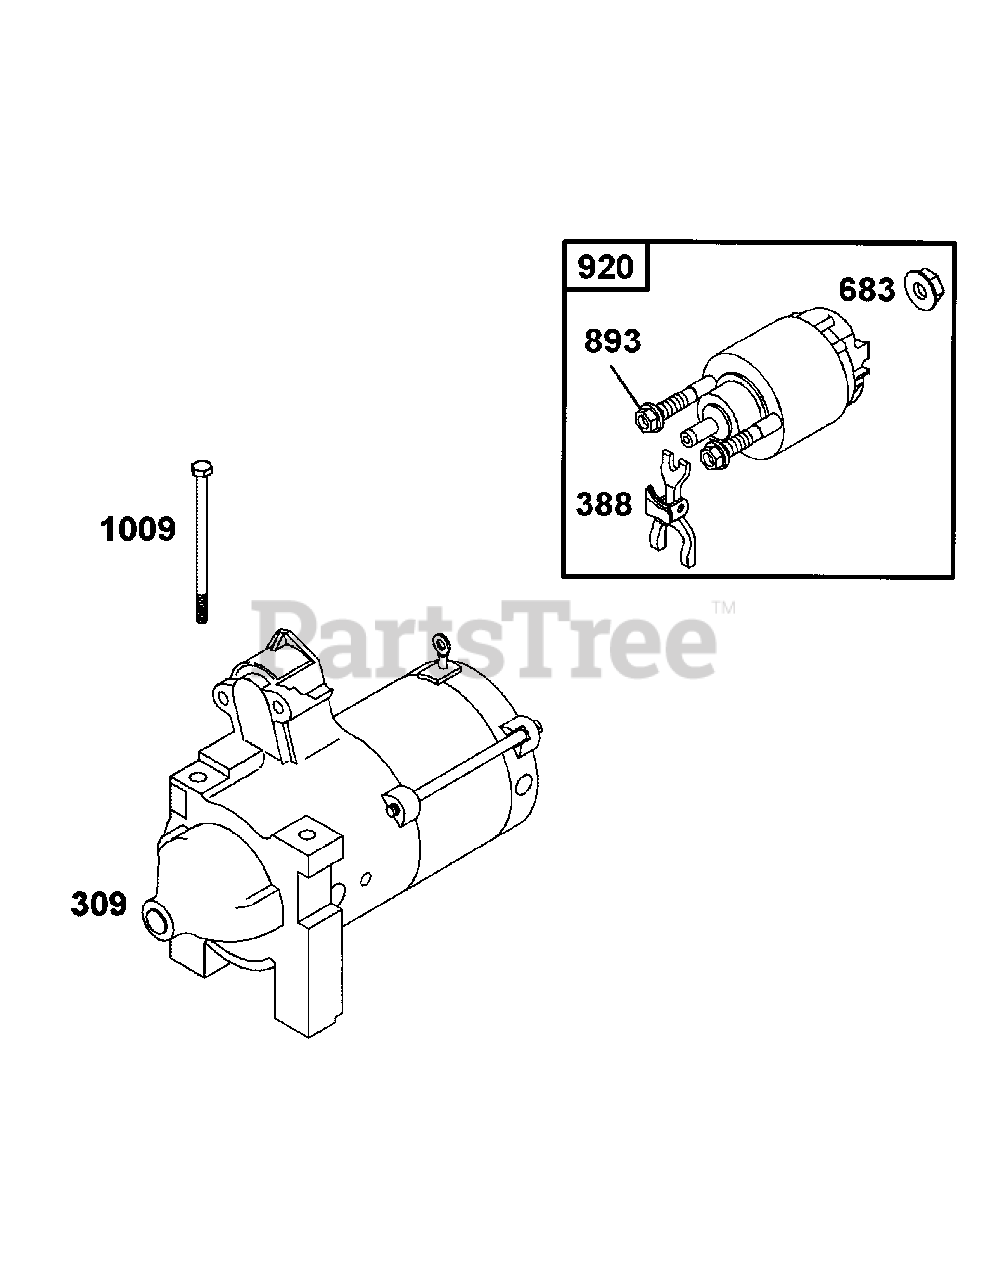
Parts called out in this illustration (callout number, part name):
309	Motor-Starter (Steel Pinion)
388	Lever-Pinion Drive
683	Nut (Starter Solenoid)
893	Nut (Starter Solenoid)
920	Solenoid-Starter
920	Solenoid-Starter (Starter Motor)
1009	Screw (Starter Motor)
